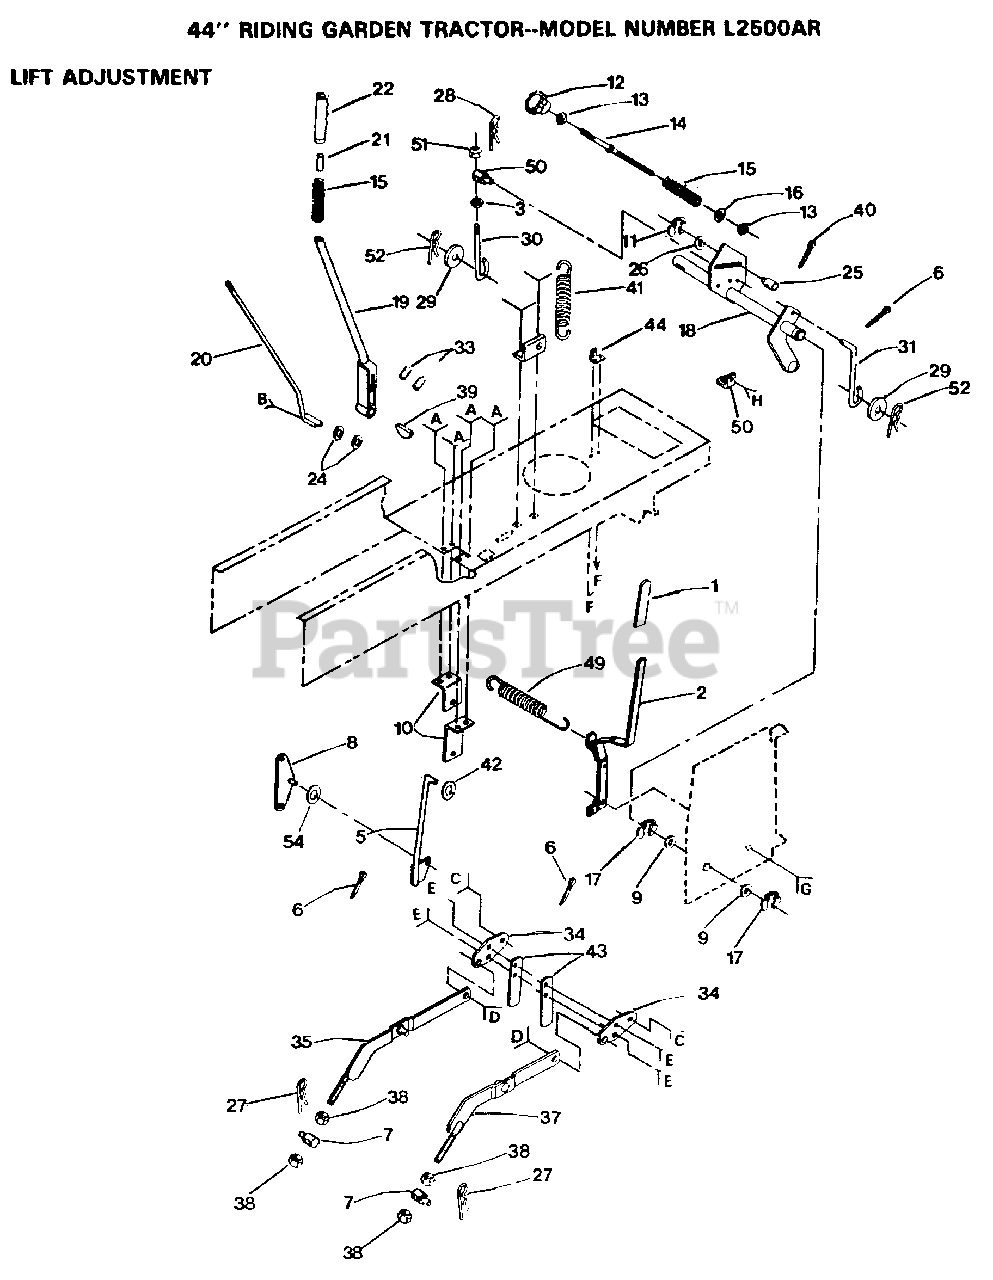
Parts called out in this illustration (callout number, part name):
1	Grip - Handle
5	ROD ASSEM YT
6	COTTER PIN
8	"T, BELLCRANK"
9	WASHER
10	"BRKT,BELLCRAN T"
11	KLIP RING
13	NUT
14	ROD ADJUST LT
15	SPRING T
16	WASHER
17	RING
19	LEVER ASSY LT
22	GRIP
25	TRUNION T
26	WASHER
27	SPRING H
29	WASHER
30	LINK LIFT LT
31	LIFT LINK LT
34	"BRACKET, SUSPE T"
38	NUT
41	IDLER SPRING
42	WASHER
44	BRACKET LT
49	"SPRING.EXT.8.5"""
51	NUT.HEX.3/8-16UNC
52	SPRING.RETAINER
